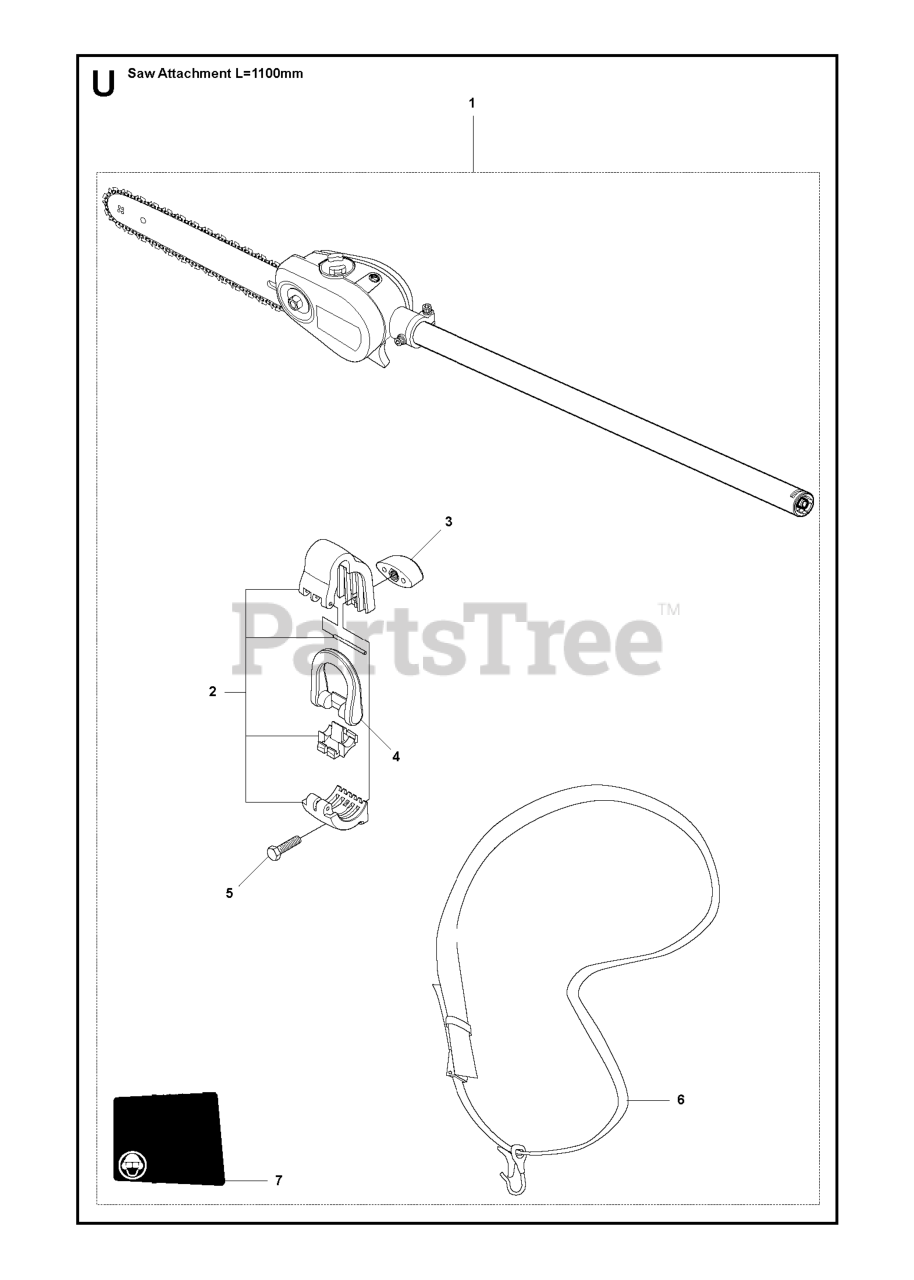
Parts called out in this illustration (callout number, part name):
1	Dx Pole Saw Attachment
2	HANGING BRACKET
5	SCREW M6S 5X20
6	Harness-w/o warning
6	Harness - Diagonal with sign
7	DECAL
